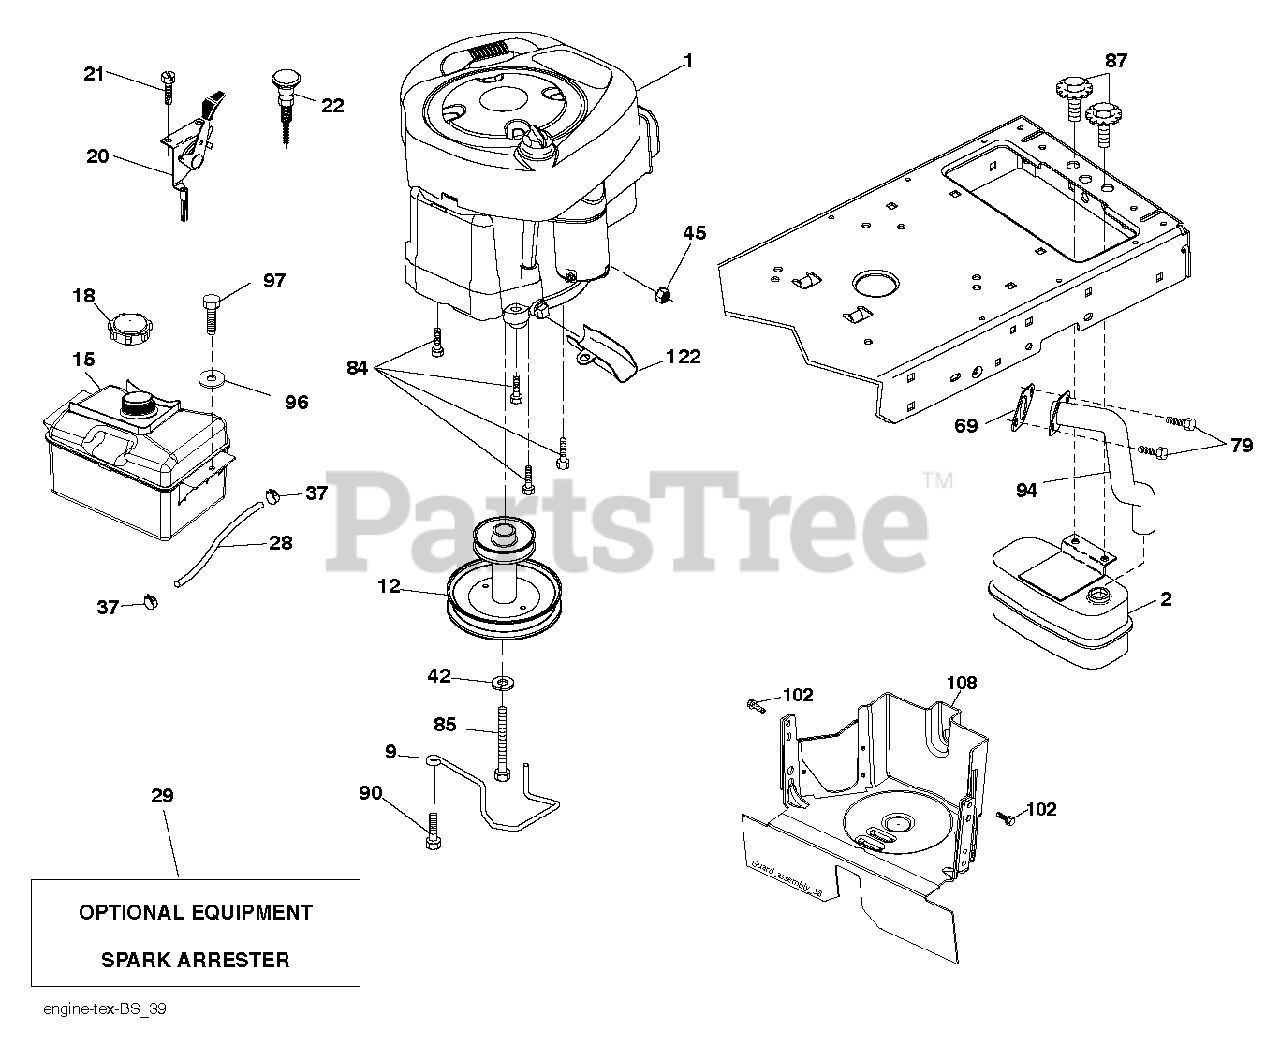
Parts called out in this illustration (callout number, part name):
2	Muffler, Single Cylinder Kohler/B&S
9	Belt Keeper, 4 25"2 Blt 431
12	PULLY ENGINE
18	CAP ASM.FUEL.2.25"FR.
20	CONTROL.TH/CK.C.
21	SCREW.#10 X 0.750.BOS THREAD
28	LINE.FUEL.20
29	ARRESTER SPARK (OPTIONAL)
37	HOSE CLAMP
42	LOCKWASHER
45	NUT
69	REPL BY 532 27 22-93
79	SCREW.SOCKET HD.5/16-1
84	SCREW.3/8-16
85	BOLT HEX 7/16-20X4-1/4"
87	BOLT, 5/16-18 X 1 3/4
90	SCREW 3/8-16X1
94	Exhaust Tube, B&S 28/31
97	SCREW HEXWSHR 1/4-20X3/4
102	SCREW 5/16-18X1
122	EXTENSION DRAIN OIL
